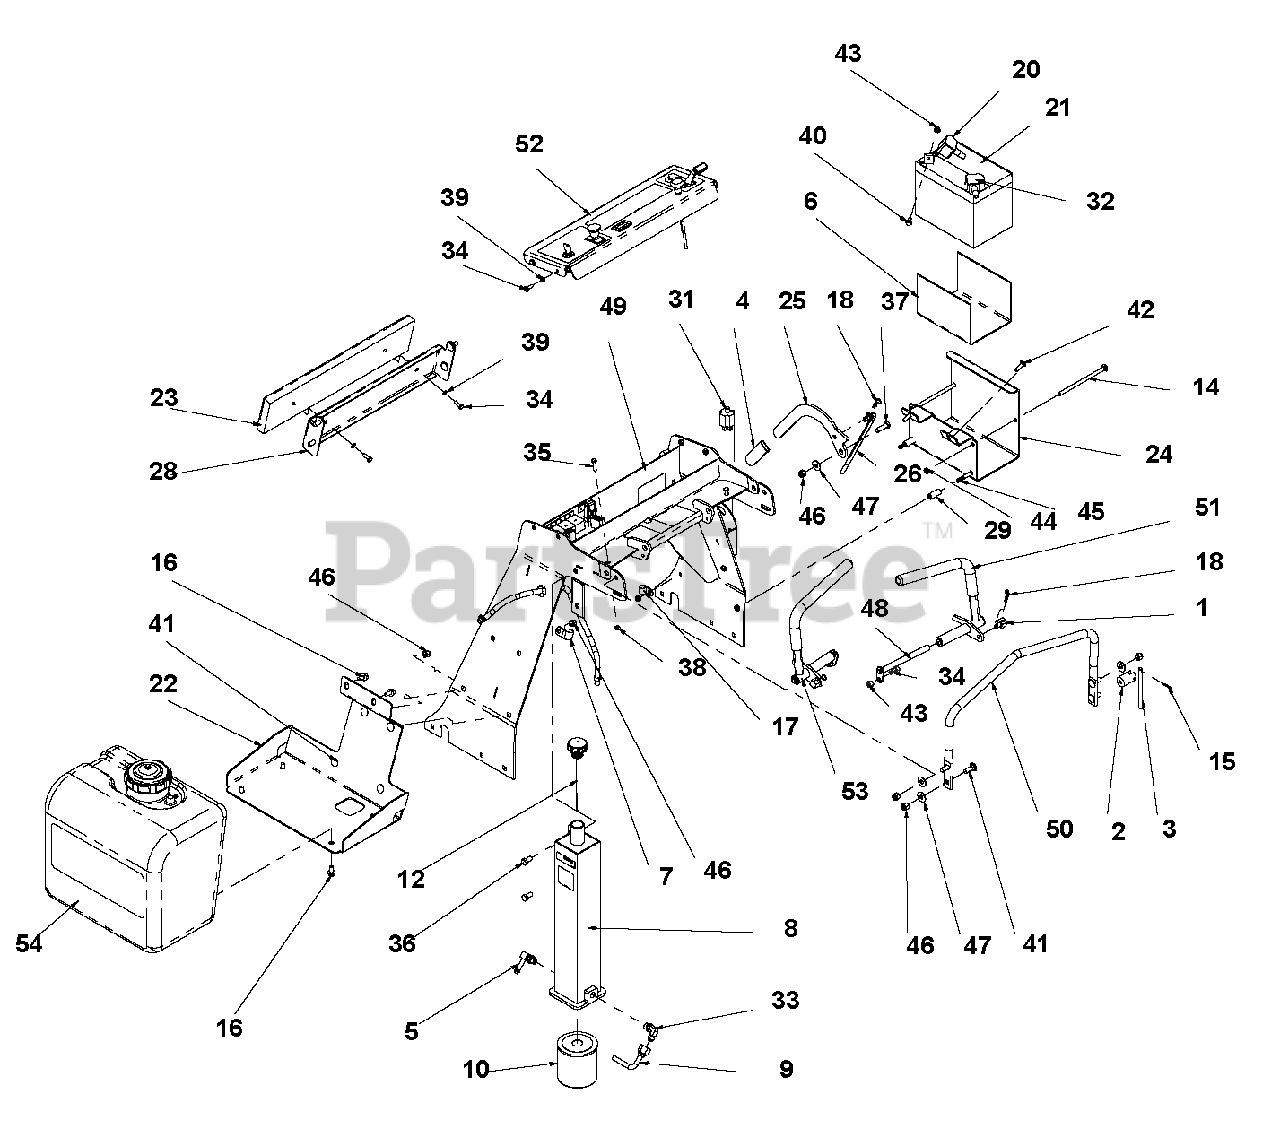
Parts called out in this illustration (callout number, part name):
1	SWIVEL
2	BASE, SPEED CONTROL LOCK
4	GRIP
5	FTG-ADPTR .562-18 ST THD
6	ISOLATOR PAD, BATTERY
7	P-CLIP, .750 INSULATED
8	HYDRAULIC RESERVOIR, INC DECAL
9	ELBOW FITTING
10	ELEMENT, OIL FILTER
11	CLAMP
12	CAP
13	HOSE, 1/4" ID LOW PERM FUEL 50
14	BOLT, 3/8-16 X 3-3/4 CHCS
15	PIN, SPRING 5/32 X 1
16	SCREW,HEX,FL,JDS123,M8X1.25X16
17	P-CLIP, .500 INSULATED
18	PIN-HAIR INT .09X1.65 PL
19	GROMMET, ROUND RUBBER .625X.19
20	CABLE, BATTERY STARTER 48"
21	BATTERY, 12V-U1-CCA270MIN
22	BRACKET, FUEL TANK MOUNTING
23	PAD, THIGH
24	TRAY, BATTERY
25	LEVER, BRAKE
26	LINK, BRAKE Y
27	BUSHING, BRAKE PIVOT Y
28	PAD, THIGH
29	BUSHING, .364X.540X1.250 Y
30	HARNESS, WIRING
31	SWITCH, NO-NO-NC GREY PLUNGER
32	CABLE, BATTERY GROUND 25"
33	ADPT 2503-6-6
34	BOLT, 1/4-20X.750 HEX 5 Y
35	BOLT, 1/4-20X1.00 HEX 5 Y
36	BOLT, 3/8-16X.750 HEX 5 Y
37	BOLT, 3/8-16X1.25 HEX 5 Y
38	QUICK START SHEET
39	WDMT,IDLER PIVOT RAPID XZ 52"
40	PLATE, ENGINE MOUNT
41	BOLT, 3/8-16X1.00 CRG 5 SN Y
42	BOLT, 5/16-18X1.00 CRG 2 Y
43	LOCKNUT, 1/4-20 WHIZ Y
44	LOCKNUT, 5/16-18 NYLOC Y
45	BOLT, 5/16-18X2.00 CRG 5 Y
46	LOCKNUT, 3/8-16 NYLOC Y
47	WASHER, .375 REG FLAT Y
48	WLDT, PIN AND LOCK Y
49	WLDT, ARIENS CONSOLE W/DECALS
50	SUPPORT, HANDLE PAINTED
51	LH CONTROL LEVER W/GRIP
52	ASSEMBLY, CONSOLE ARIENS
53	RH CONTROL LEVER W/GRIP
54	TANK ASSY,EPA FUEL,ARIENS
